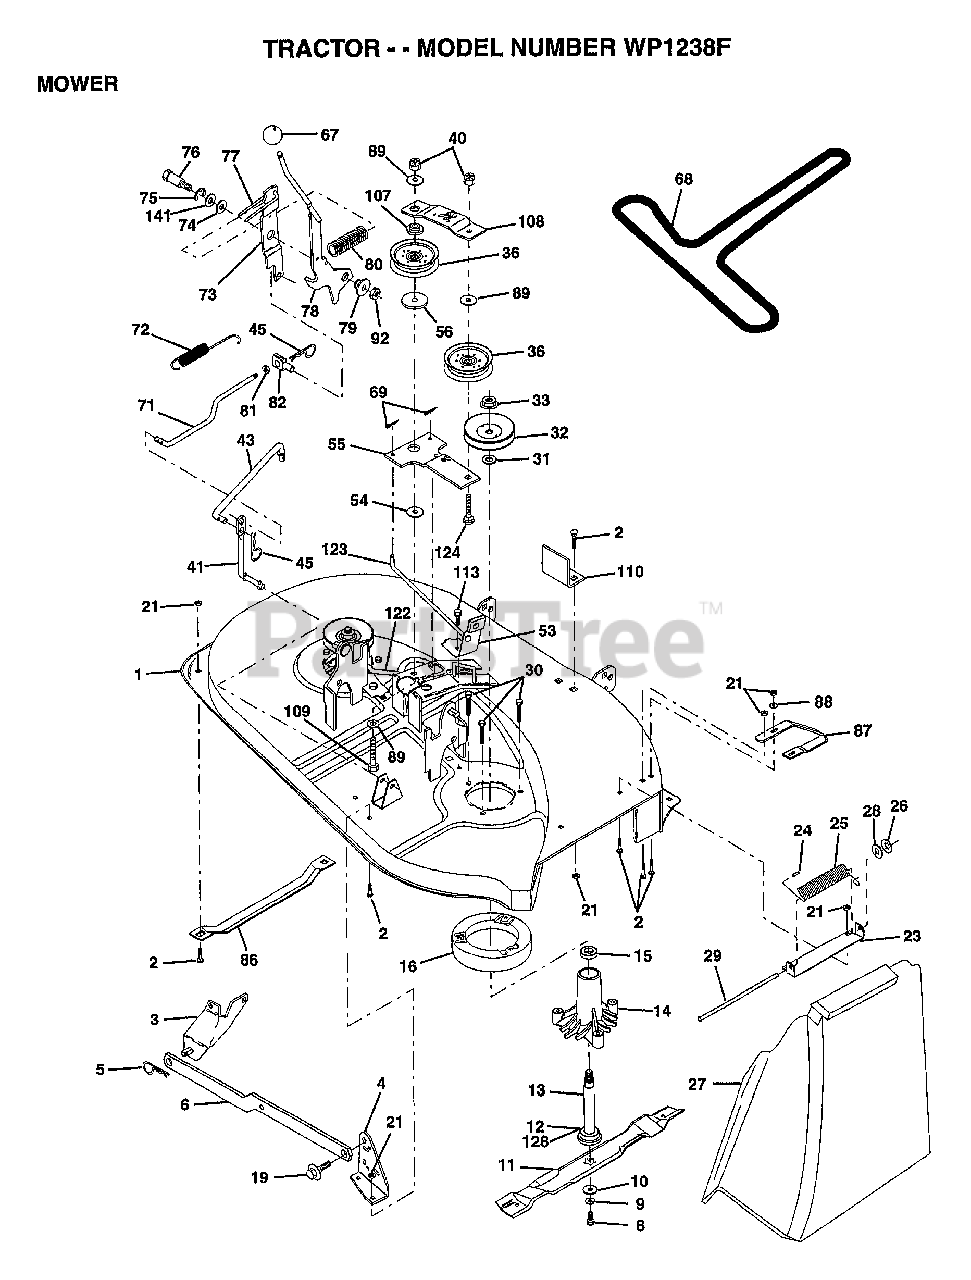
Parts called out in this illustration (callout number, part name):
2	BOLT
3	BRKT ASM SWAY BAR
4	BRKT DECK SW BAR
8	BLADE BOLT
10	WASHER.HARD.BLADE
11	"BLADE.38"" HIPERF"
12	BEARING.BALL
14	HSG ASM MANDREL
15	BEARING
16	STRIPPER RND MWR
19	BOLT SHD 5/16-18
23	BRKT DEFLECTOR
24	CAP-SLEEVE LT
25	SPRING TORSION
26	NUT PUSH M
27	DEFLECTOR-SHLD T
28	WASHER
29	ROD-HINGE T
30	"SCREW-THD ROLL,WA"
31	WASHER
32	PULLEY.MANDREL.38
36	FLAT IDLER PULLEY
41	PIVOT ROD
43	CLUTCH ROD SECOND
45	RETAINER M
53	BRAKE ASM
54	HARDENED WASHER
55	IDLER ARM ASSY
56	SPACER RETAINER
67	KNOB.RD.7/16-14
68	BELT.V.T-PATH
71	ROD CLUTCH 38/42
72	RETURN SPRING
73	CLUTCH ARM SECOND
74	WASHER
75	RING
76	SHOULDER BOLT
77	SPRING KEEPER
78	LEVER.ASM.CLUTCH
79	BUSHING
80	SPRING.CLUTCH.MWR
81	NUT
82	TRUNION ADJ
86	RUNNER-LH M
87	RUNNER RH
88	WASHER M
89	WASHER GT
92	NUT
107	RETAINER SPACER
108	IDLER ARM STIFF
109	BOLT
110	UPSTOP DECK FT 38
113	SCREW
122	BRAKE ROD LH
123	BRAKE ROD RH
124	BOLT
128	WASHER.FELT.
141	WASHER .T
